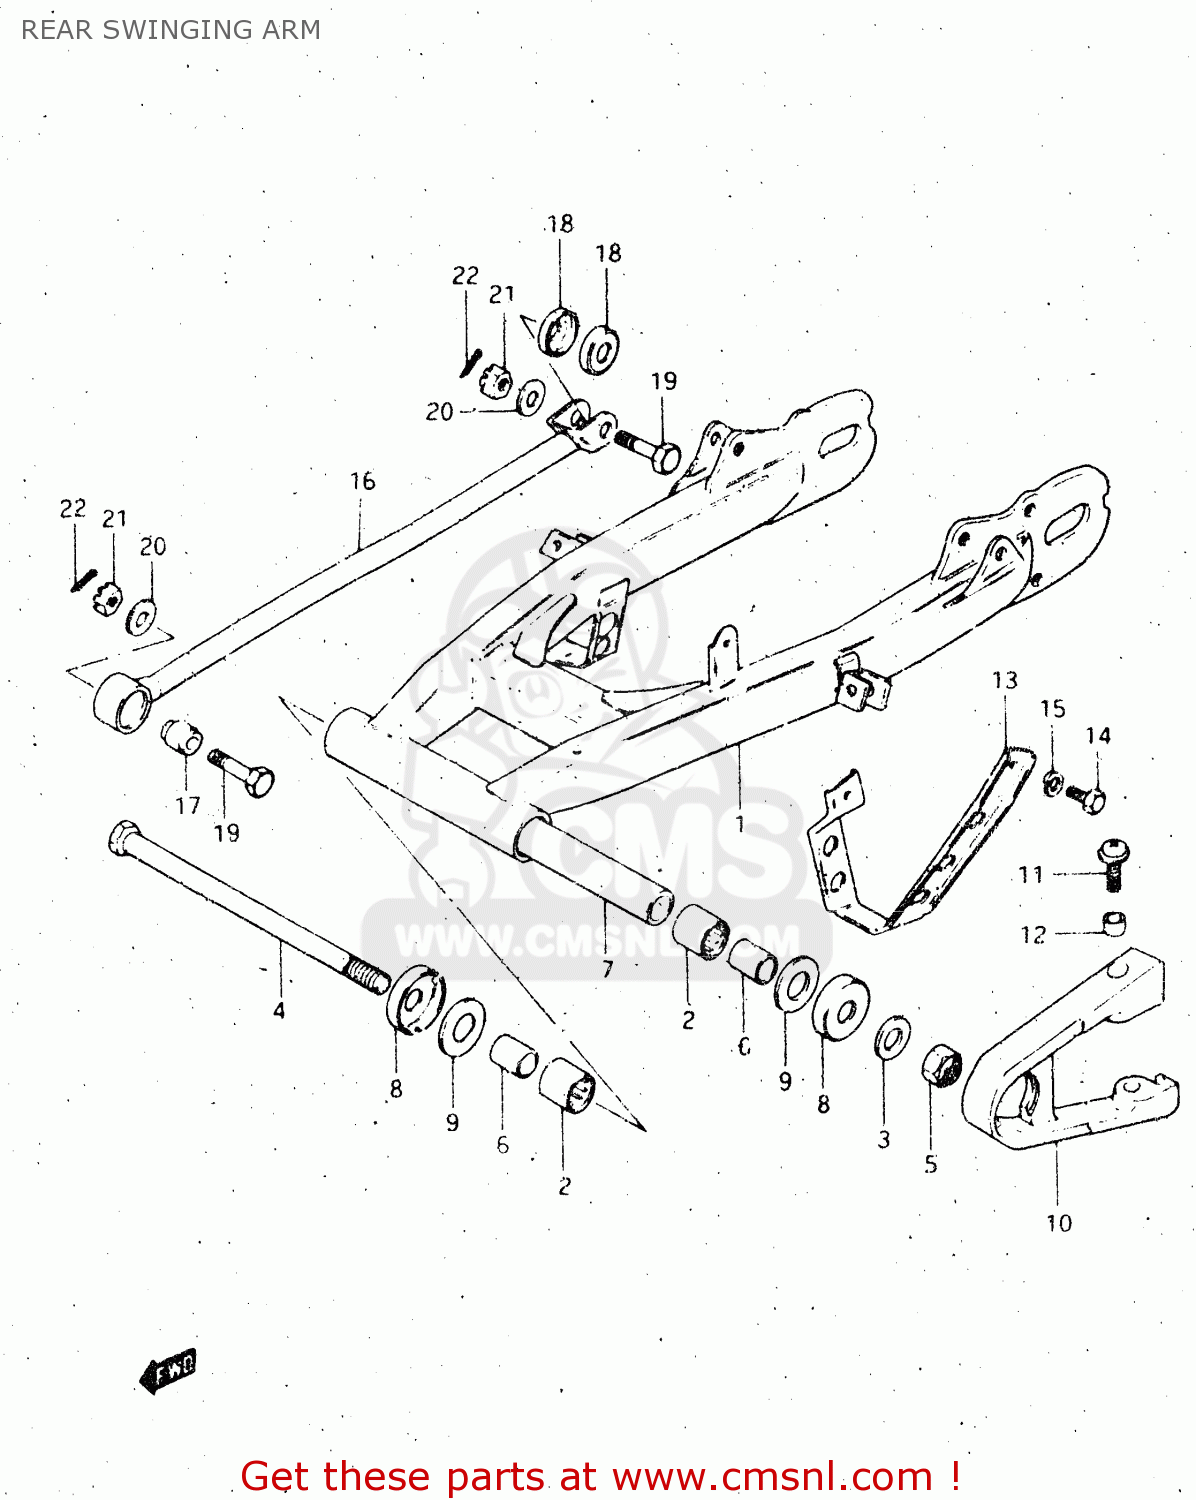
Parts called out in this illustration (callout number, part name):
1	ARM,REAR SWING
2	BEARING(22X29X20)
3	WASHER
4	SHAFT,REAR SWING ARM
5	NUT 16MM
6	SPACER,RR SWGARM PIVOT
7	SPACER (16.2X21.7X142)
8	COVER,RR SWGARM DUST SEAL
9	WASHER
10	BUFFER,CHAIN TOUCH DEFLECTOR
11	SCREW,CHAIN TOUCH DEFEND
12	SPACER (5.5X8X4)
13	GUIDE,CHAIN
14	BOLT
15	LOCK WASHER
16	LINK,REAR TORQUE
17	BUSH
18	19
19	BOLT 8X29.5
20	WASHER
21	NUT 8MM
22	PIN 20X20
